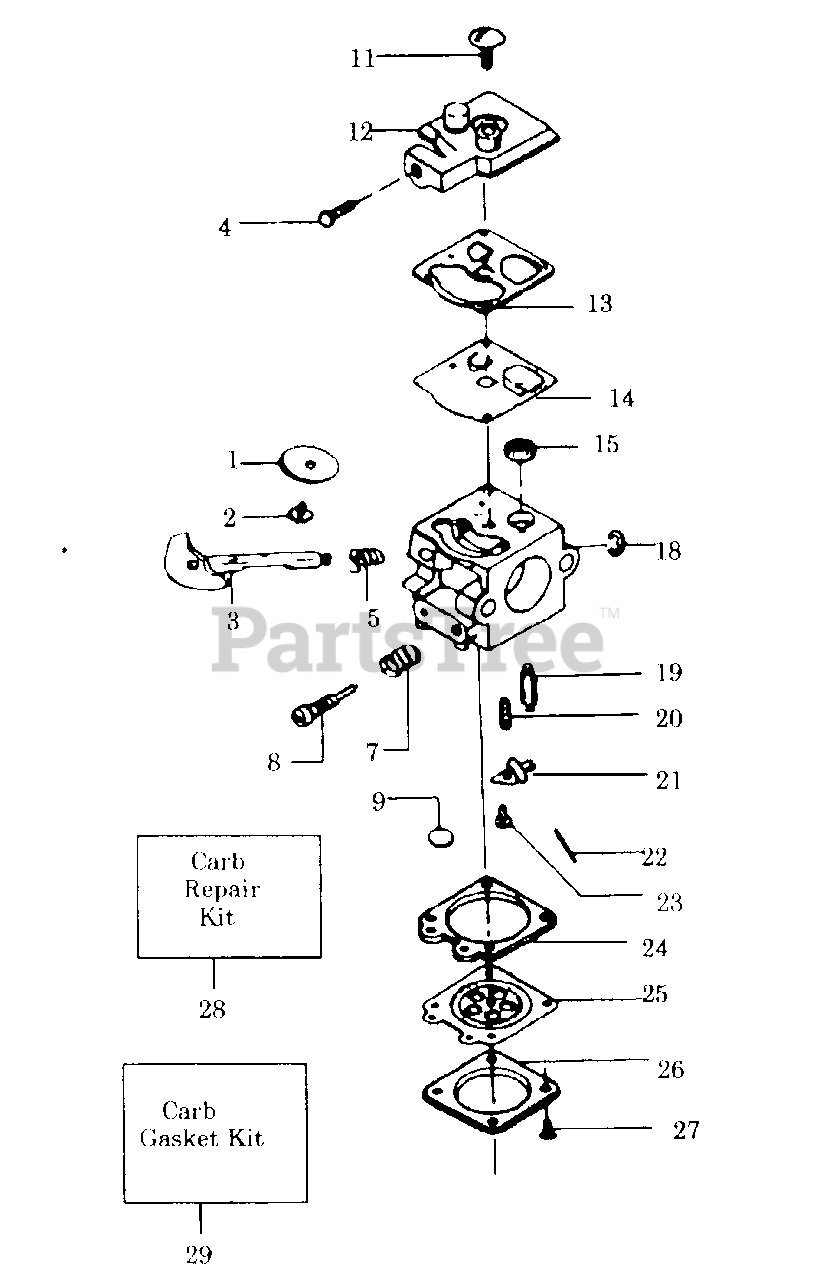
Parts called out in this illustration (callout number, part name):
1	Valve Throttle
2	Screw-Throttle Valve
3	Shaft Ass'y.-Throttle
4	Idle Speed Screw
5	Spring-Throttle Return
7	Spring-High Speed Mixture Needle
8	Needle-High Speed Mixture
9	Plug-5/16 Dia. Welch
11	Screw-Pump Cover
12	Cover-Fuel Pump
13	Gasket-Fuel Pump
14	Diaphragm-Fuel Pump
15	Screen-Fuel Inlet
18	Ring-Throttle Retainer
19	Valve-Inlet Needle
20	Spring-Metering Lever
21	Lever-Metering
22	Pin-Metering Lever
23	Screw-Metering Lever Pin
24	Gasket-Metering Diaphragm
25	Diaphragm-Metering
26	Cover-Metering Diaphragm
27	Screw Ass'y.-Metering Cover
28	Kit-Carb. Kwik Repair
29	Kit-Carb. Gasket/Diaphragm
